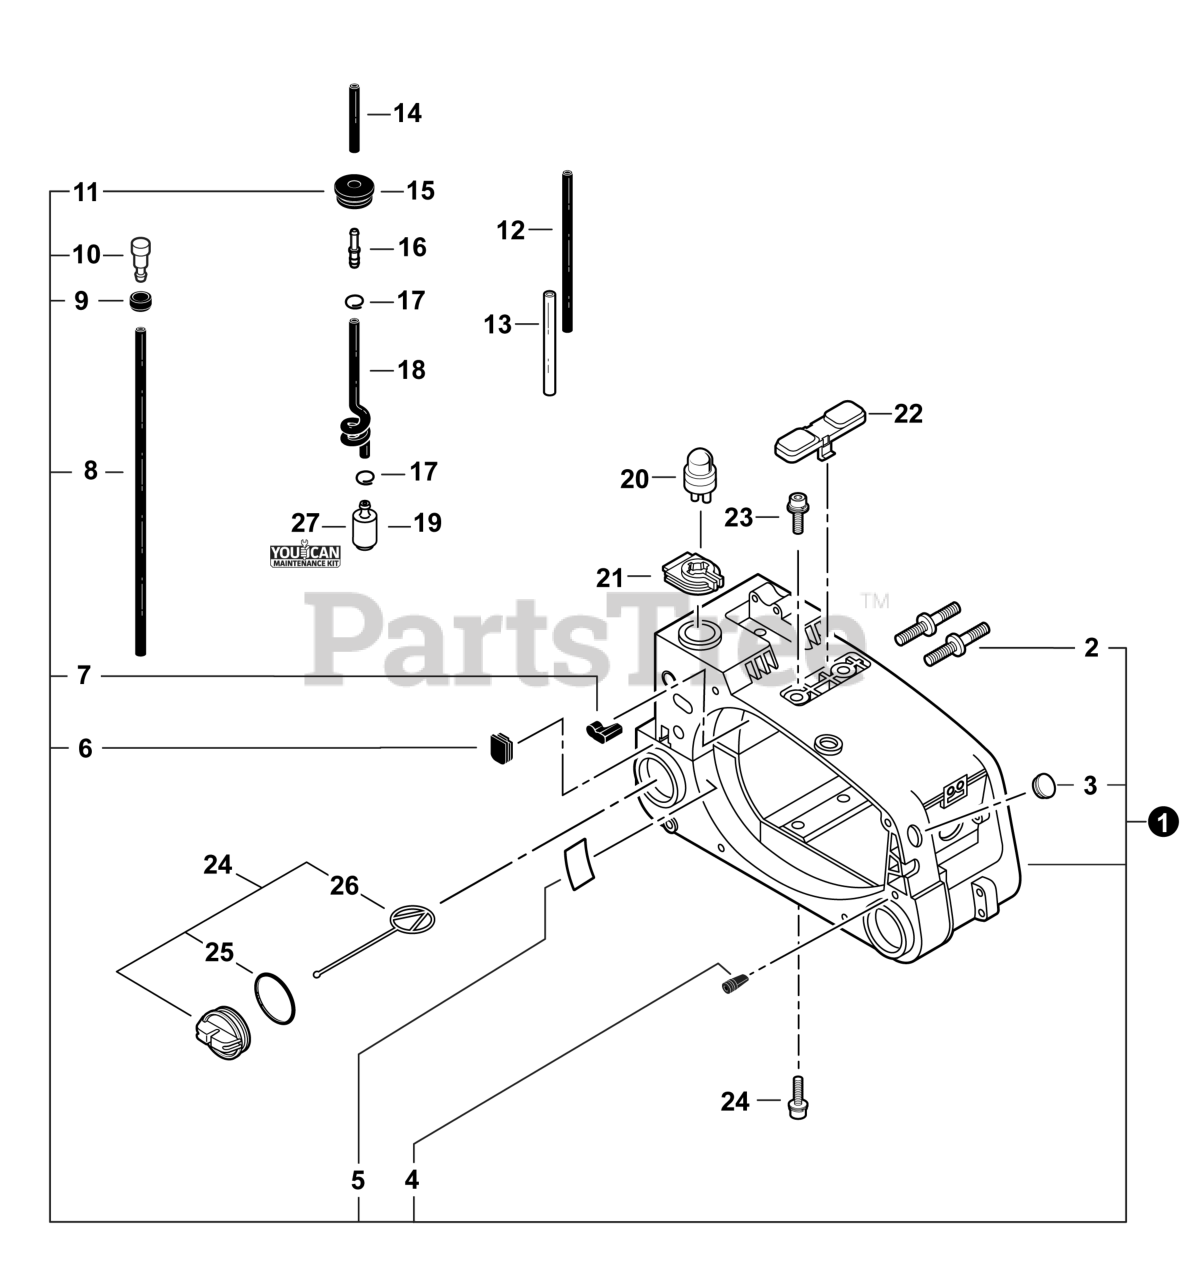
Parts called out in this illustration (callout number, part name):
1	COVER ASSY, ENGINE
2	BOLT, STUD 6
4	VENT ASSY
5	SHIELD, HEAT
8	PIPE, FUEL 3x5x150 BLACK
9	HOLDER, VENT
10	VENT ASSY
11	GROMMET, FUEL
12	PIPE, FUEL 3x5x70 BLACK
13	PIPE, FUEL 2x4x42 CLEAR
14	PIPE, FUEL 3x6x36 BLACK
15	GROMMET, FUEL
16	CONNECTOR, PIPE 5x3.5
17	CLIP 6.5 MM
18	PIPE, FUEL 3x6x56 BLACK
19	FILTER, FUEL
20	BULB, PURGE
21	BRACKET, BULB
22	COVER, TOP
23	BOLT 5x16
24	CAP ASSY, FUEL - ORANGE
26	CONNECTOR, CAP L= 60 MM
27	TUNE-UP KIT - YOUCANT
